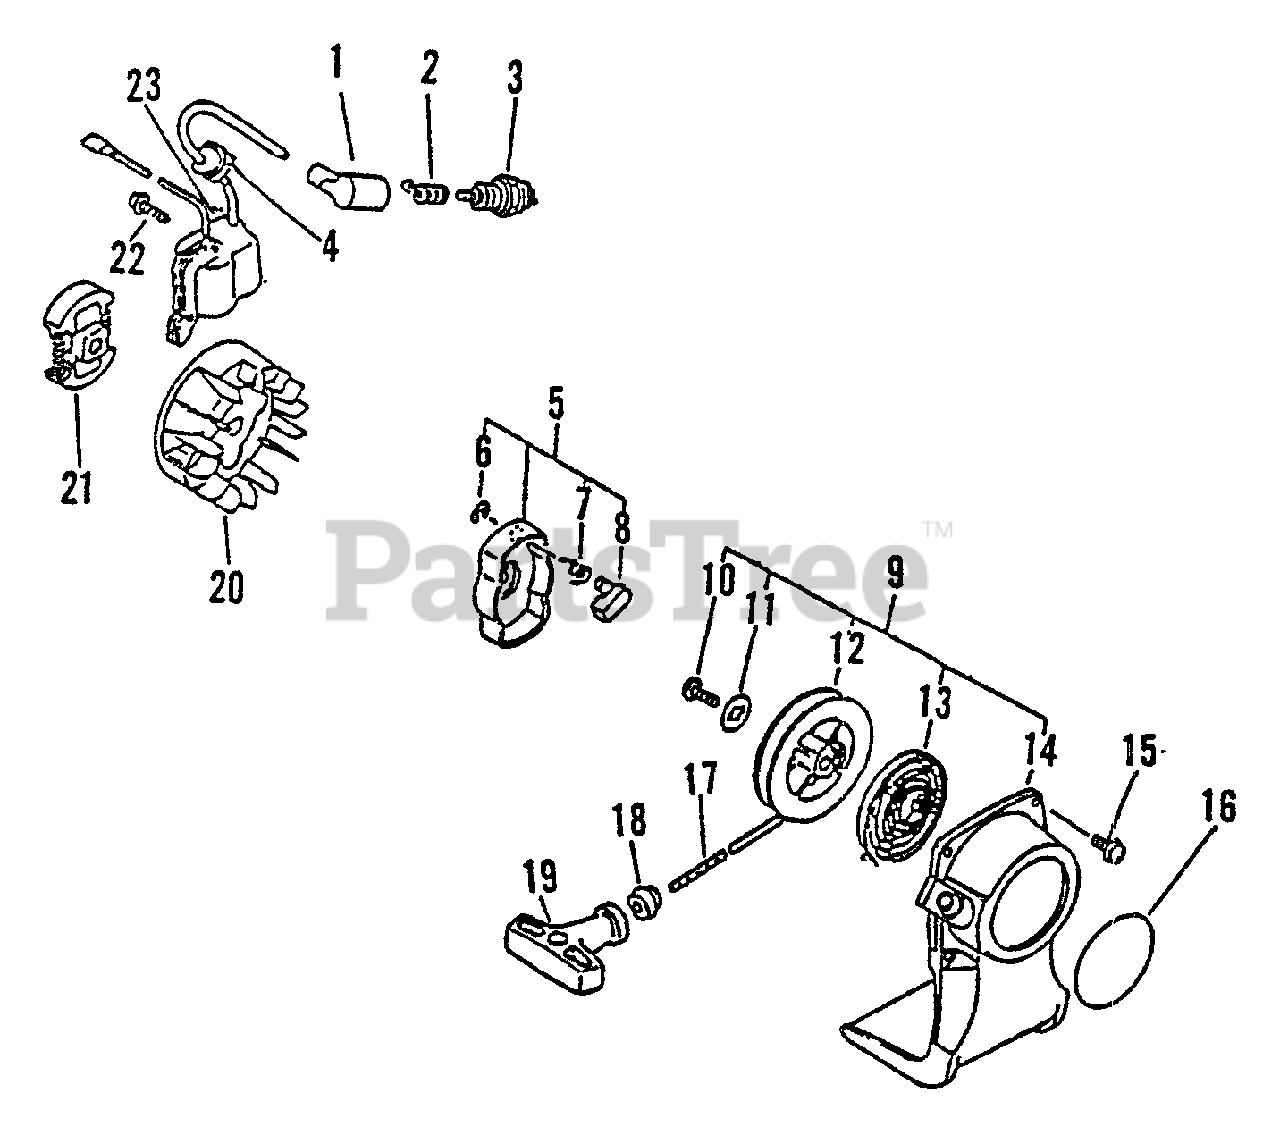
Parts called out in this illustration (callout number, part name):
1	CAP, SPARK PLUG
2	TERMINAL, SPARK PLUG CAP
3	SPARK PLUG -- BPM-7A
4	GROMMET
5	STARTER PAWL ASSY
6	RING, RETAINING - 4
7	SPRING, RETURN
8	PAWL, STARTER
9	STARTER ASSY
11	WASHER
12	REEL, ROPE
13	SPRING, REWIND
14	CASE, STARTER - BLUE
15	SCREW - 4X16
16	LABEL - LESCO
17	ROPE, STARTER - 3X890
18	GUIDE, ROPE
19	GRIP, STARTER
20	FLYWHEEL
21	CLUTCH ASSY
22	SCREW - 4X22
23	COIL, IGNITION
